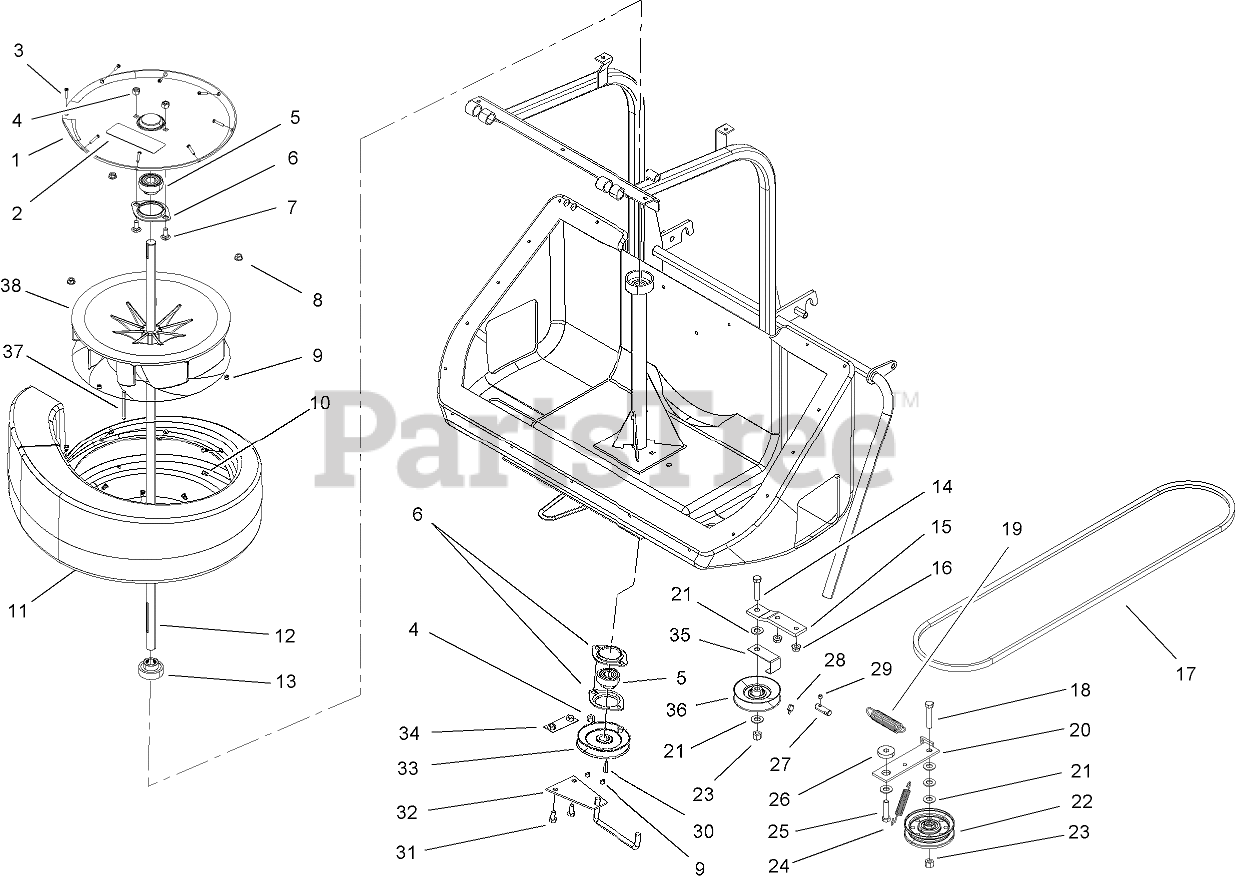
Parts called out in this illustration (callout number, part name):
1	COVER-SCROLL
2	DECAL-HAZARD, ADD WEIGHT
3	SCREW-PPH
4	NUT-LOCK, NI
5	BEARING
6	FLANGE
7	BOLT-CARR
8	NUT-HF
9	SCREW-SET, HSH
10	NUT-INSERT
11	SCROLL
12	SHAFT
13	BEARING
14	SCREW-HH
15	Bracket
16	NUT-HF
17	Belt-V
18	SCREW-HH
19	Spring-Extension
20	Arm-Idler
21	WASHER-FLAT
22	IDLER-FLAT
23	NUT-LOCK, NI
24	Spring-Extension
25	SCREW-HH
26	WASHER-FLANGE
27	END-CABLE
28	Grommet-Cable
29	SCREW-SET, HSH
31	SCREW-HH
32	Guide-Belt
33	PULLEY-V
34	Plate-Mounting
35	Guide-Belt
36	Pulley-V
